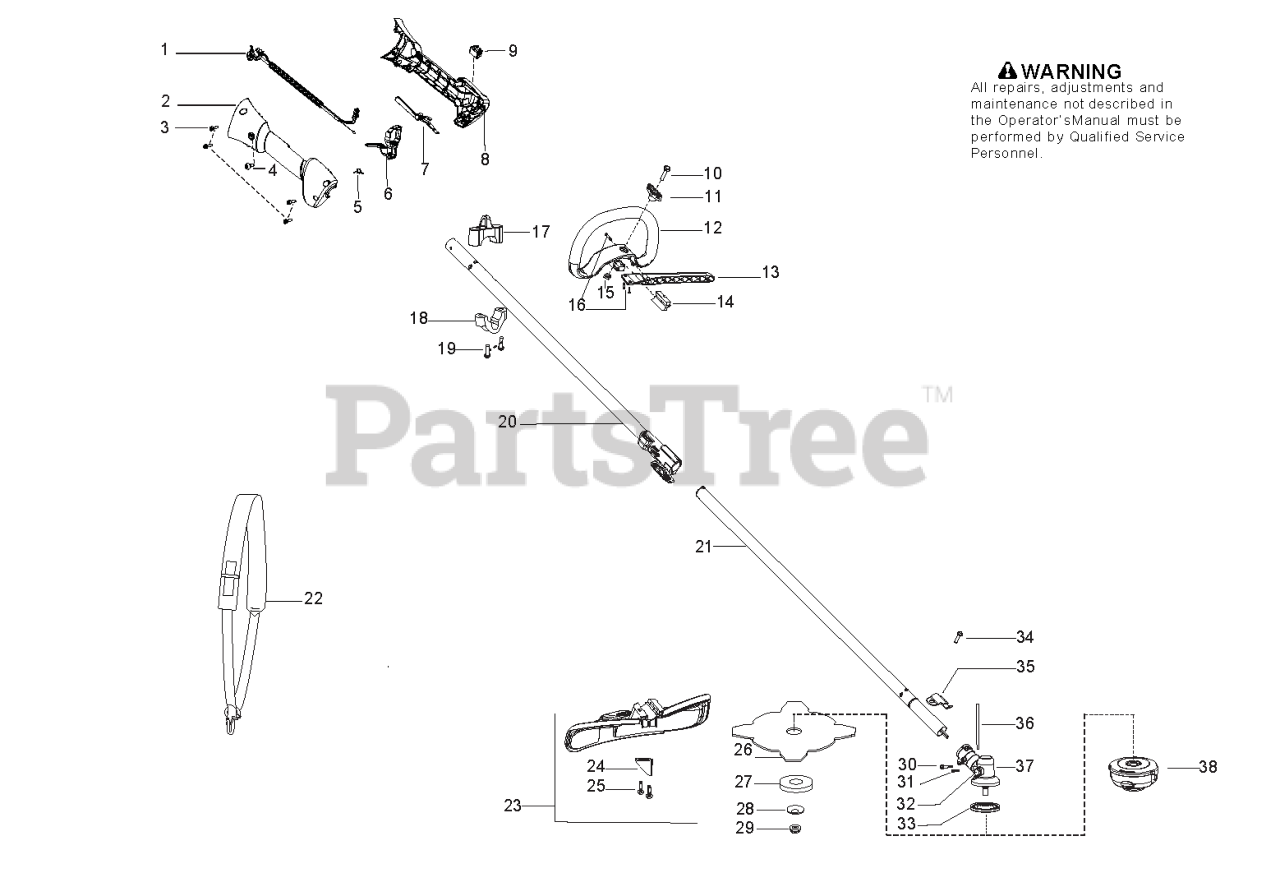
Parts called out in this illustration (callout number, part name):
1	ASSY CABLE / WIRE HARNESS
2	HSG THROTTLE RIGHT HVA
3	SCREW M4 X 1.75 PT 16MM
4	SCREW-10-14 X 1/2 PLASTITE
5	SPRING TRIGGER
6	TRIGGER THROTTLE HVA ORANGE
7	THROTTLE LOCKOUT HVA ORANGE
8	HSG THROTTLE LEFT HVA
9	SWITCH
10	SCREW M6X50
12	HANDLE LOOP
14	SPACER PLASTIC
16	SCREW IHSCFTO
17	CLAMP HARNESS UPPER
18	CLAMP HARNESS LOWER
20	DRIVESHAFT
21	KIT LOWER SHAFT
22	Harness - Diagonal with sign
23	KIT COBI SHIELD
24	Limiter - Line
26	Blade - Grass
27	SUPPORTING CUP
28	SUPPORT FLANGE
29	GEARHEAD NUT - BRUSHCUTTER
30	SCREW - CARB. ADAPTOR
32	PLUG GREASE 9MM
33	DRIVE DISC
34	SCREW 1/4-20 X 7/8 (TAP
35	BRACKET SHIELD STRAIGHT SHAFT
36	LOCKING PIN
37	ASSY GEARBOX
38	T25 TRIM HEAD 10MM LH
